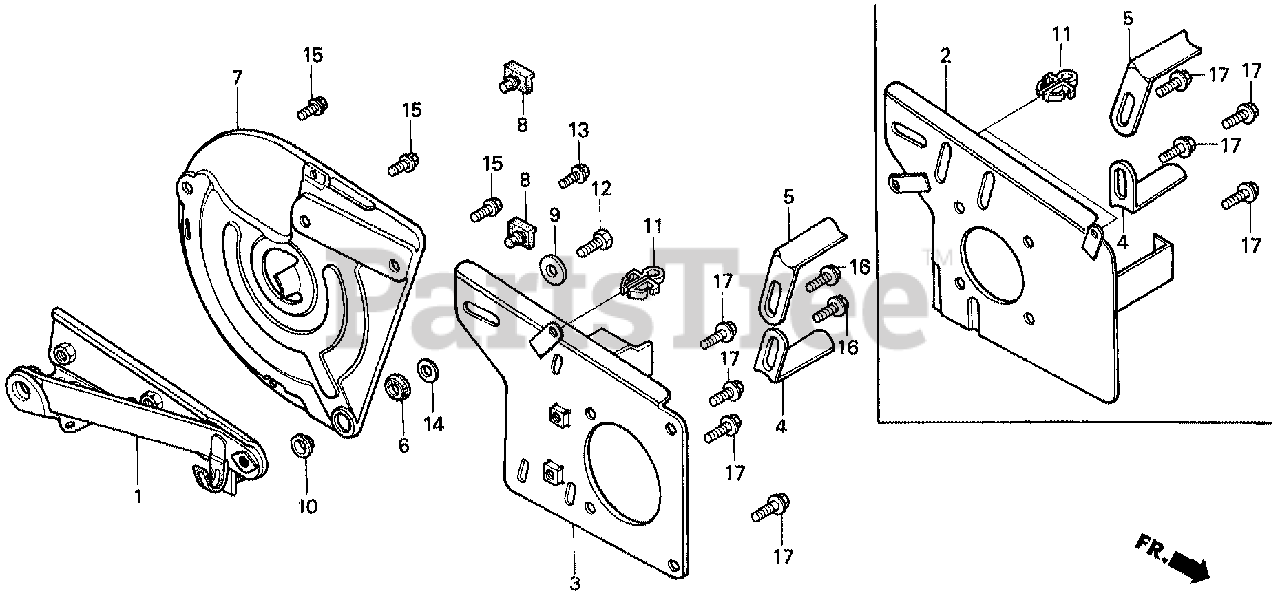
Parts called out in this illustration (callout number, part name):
1	STAY, ENGINE
3	PLATE, ENGINE ADJUSTING
4	STOPPER A, BELT (NOT AVAILABLE)
5	STOPPER B, BELT
6	GROMMET, WIRE HARNESS
7	STAY, BELT COVER
8	GROMMET, BELT COVER
9	WASHER (8MM)
10	WASHER, NUMBER BRACKET SETTING
12	BOLT, HEX. (8X16)
13	BOLT-WASHER (6X16)
13	BOLT, FLANGE (6X12)
14	WASHER, PLAIN (8MM)
15	BOLT, FLANGE (6X12)
16	BOLT, FLANGE (8X14)
17	BOLT, FLANGE (8X16)
